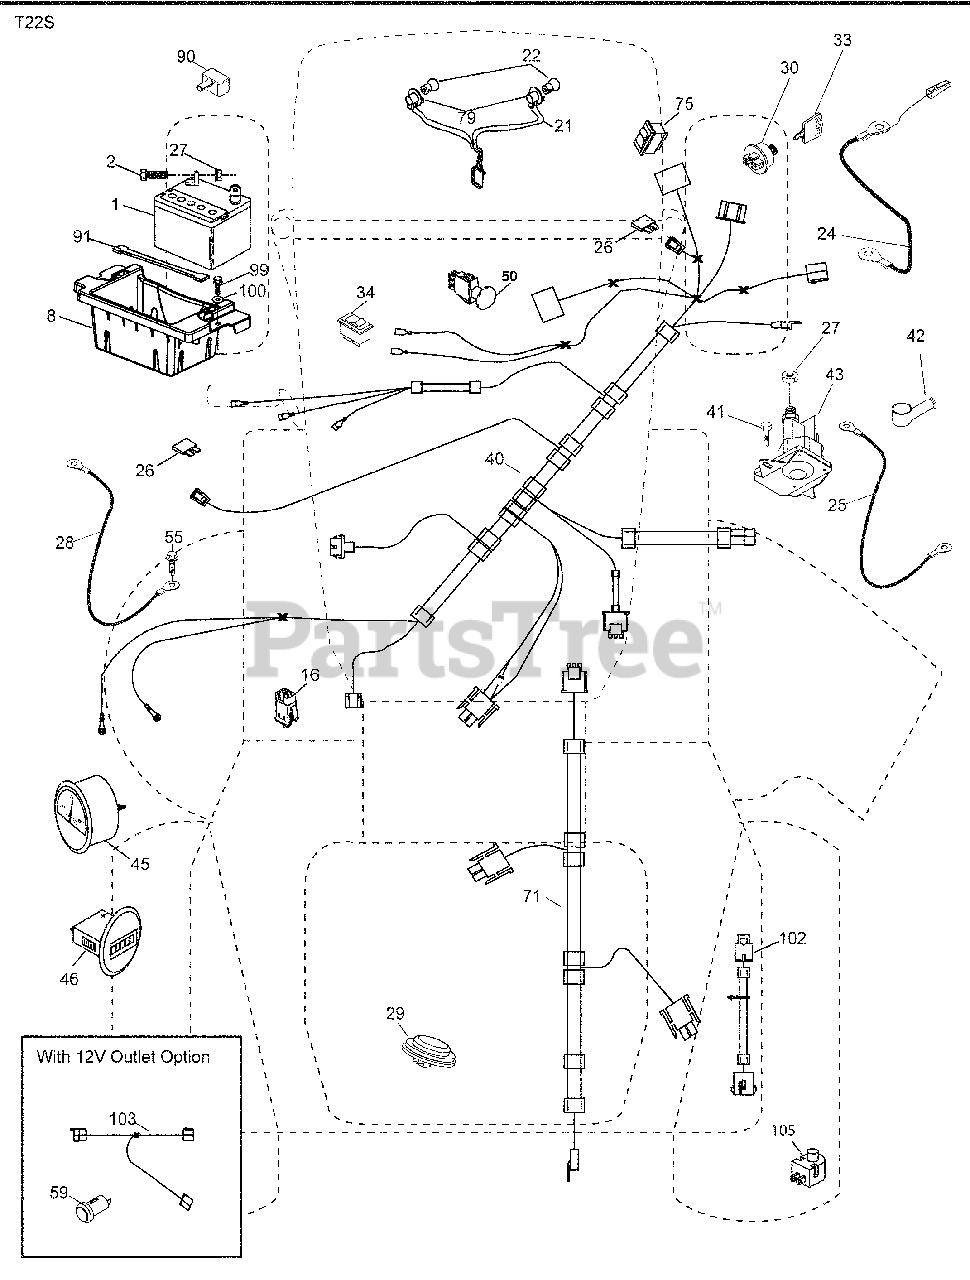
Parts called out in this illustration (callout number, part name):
1	Battery
2	Bolt Hex Hd 1/4-20 unc x 3/4
8	Battery Box
16	Switch Interlock
21	Harness Socket Light
22	Bulb, Light #1156
24	Cable Battery
25	Cable Starter
27	Nut Keps Hex 1/4-20 unc
28	Cable Ground 21" Blk 6 Ga.
29	Switch Seat
30	Switch Ign
33	Key/Chain
34	Switch Light/Reset
40	Harness Ign. Dash
41	Screw 1/4-20 unc x 1/2
42	Cover Terminal Red
43	Solenoid
45	Ammeter
46	Gauge Hourmeter
50	Switch PTO
55	Screw Thdrol 5/16-18 x 3/4
59	Outlet 12-Volt
71	Harness Ign
75	Switch Rocker Decklift
79	Socket Asm. Bulb Twistlock
90	Cover Terminal Battery
91	Strap Battery
99	Screw Hexwsh Thdrol 1/4-20 x 3/4
100	Washer 9/32 x 7/8 x 16 Ga.
102	Harness Pigtail
103	Harness Pigtail 12V Outlet
105	Switch Reverse
